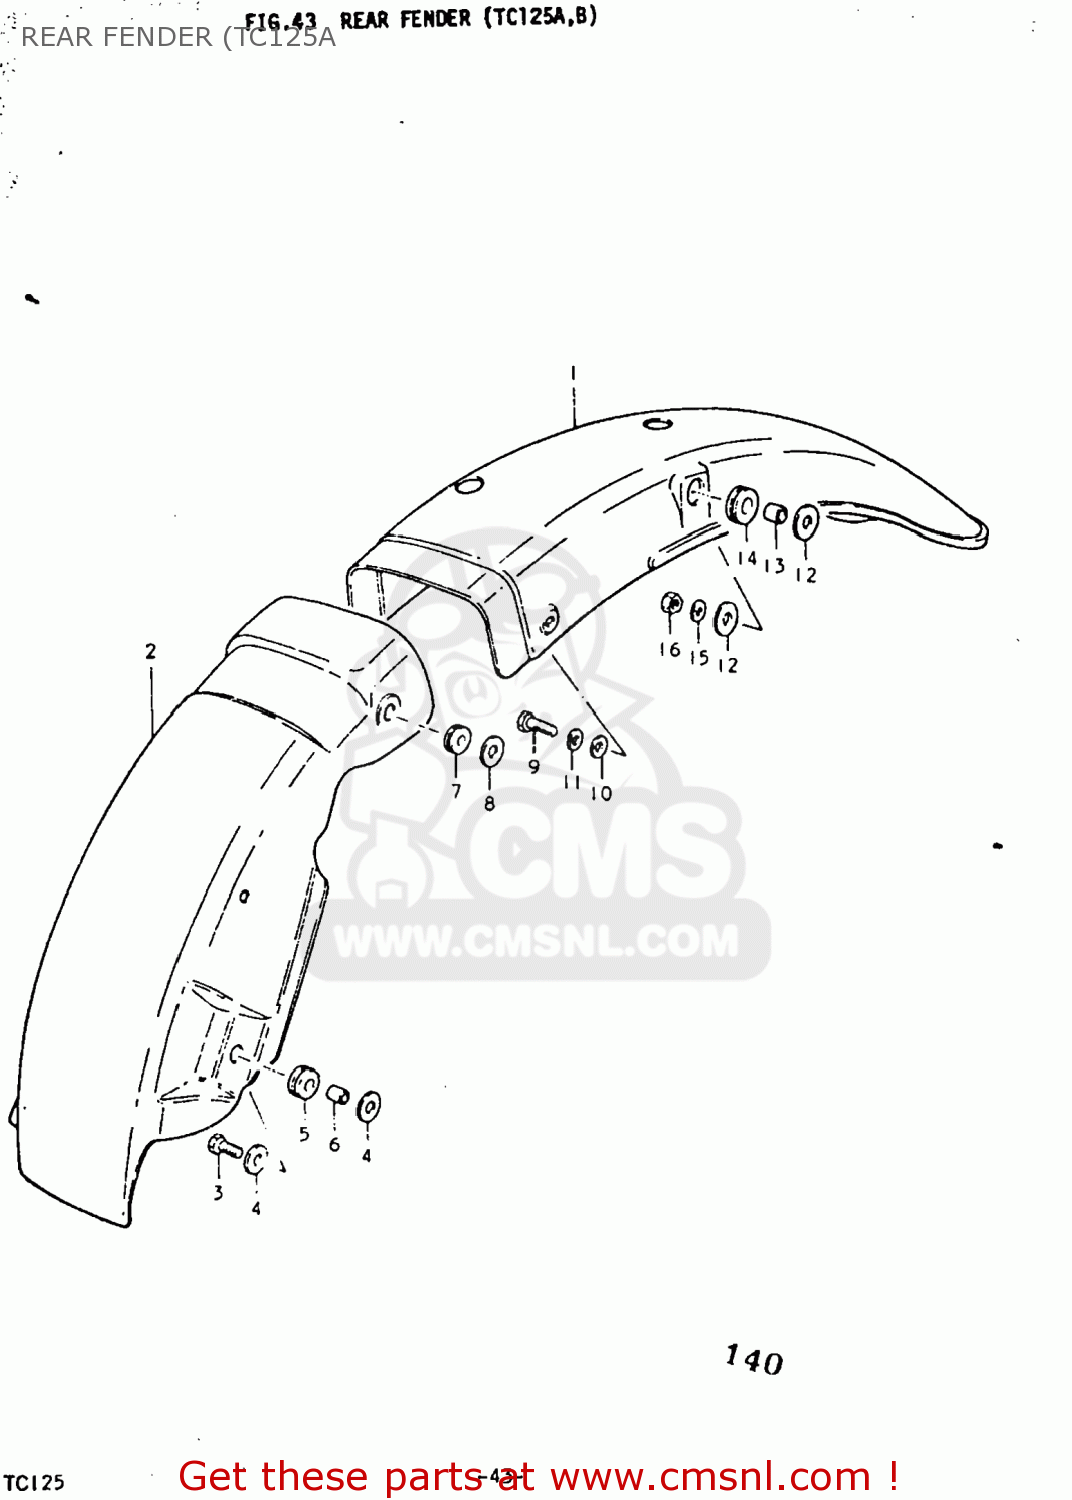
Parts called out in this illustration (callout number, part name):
1	FENDER,REAR
2	FENDER,REAR
3	BOLT
4	WASHER (6.5X20X1.2)
5	CUSHION
6	SPACER(6.1X9X7.5)
7	CUSHION
8	WASHER
9	BOLT
10	WASHER
11	LOCK WASHER
12	WASHER(10.3X25X1.5
13	SPACER
14	CUSHION
15	LOCK WASHER
16	NUT
